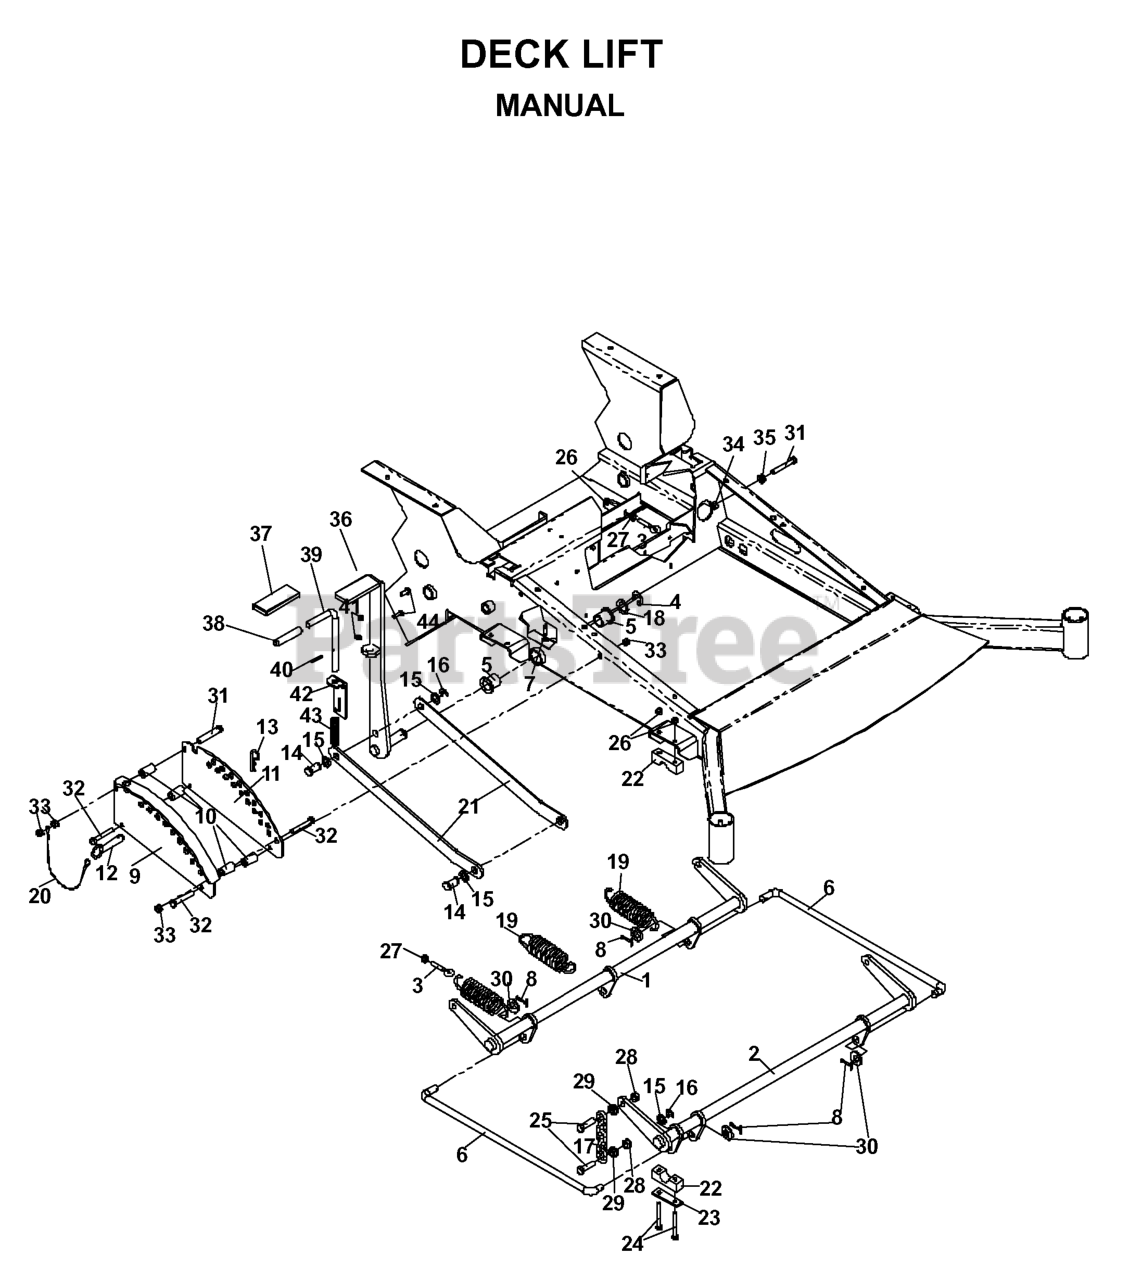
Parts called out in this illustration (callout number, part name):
1	SHAFT LIFT REAR
2	LIFT SHAFT
3	EYEBOLT, RH
4	E-RING 7/8
5	BUSHING, FLANGED
6	CONNECTING LINK
7	GREASE ZERK LONG
8	COTTER PIN
9	ADJ. PLATE WLDMNT
10	DECK LIFT SPACER
11	ADJ. PLATE PAINTED
13	HAIRPIN #4
14	CLEVIS PIN
16	E-RING 5/8
17	LIFT CHAIN
18	BSHG .875 X 1.375 X .074 ZD
19	DECK LIFT SPRING
21	LIFT LINKAGE,PAINTED
22	PILLOW BLOCK
23	REINFORCEMENT BAR
24	BOLT 5/16C X 2 1/2
25	HCS 7/16C X 1 1/2
26	NUT 5/16C CENTERLOCK
27	NUT 5/16C WHIZ
28	NUT 7/16C CENTERLOCK
29	NUT 7/16C WHIZ
30	WASHER 5/8 FLAT
31	HCS 3/8C X 2 1/2
32	HCS 3/8C X 2 1/4
33	NUT 3/8C CENTERBLOCK
34	NUT 3/8-16 NYLOC
35	NUT 3/8C WHIZ
36	LIFT LEVER WELDMENT
41	NUT 1/4C CENTER LOCK
42	PIN MT, UPPER
44	HCS 1/4C X 3/4 HCS
